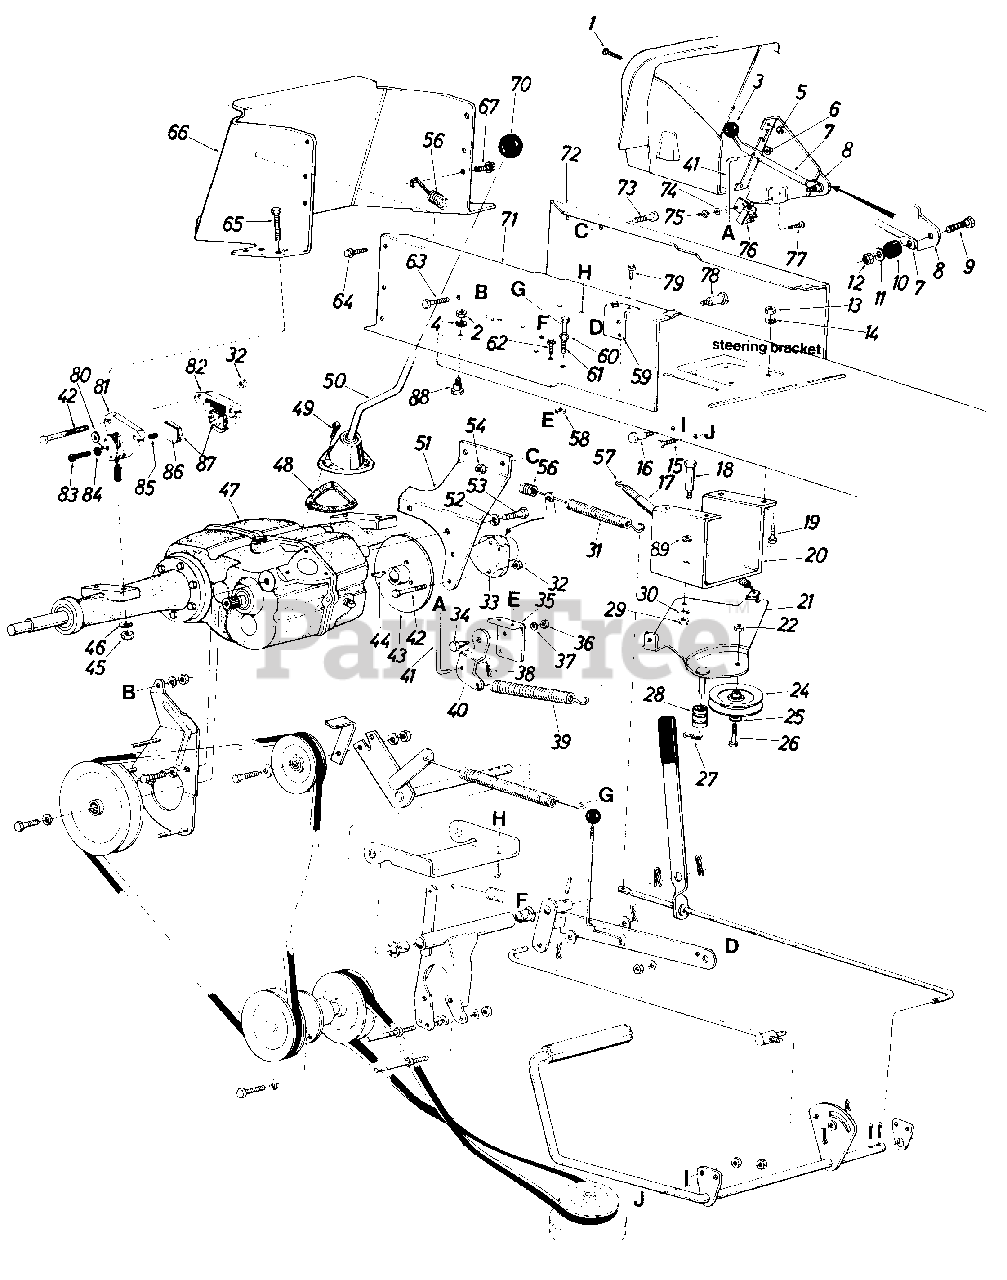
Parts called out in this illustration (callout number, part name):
1	Truss Mach. Scr. 1/4-20 x .50" Lg.
2	Hex Nut 1/4-20 Thd.
3	Knob-Blade Clutch
4	L-Wash. 1/4 I.D.
5	Hex Sems Nut 1/4-20 Thd.
6	Push Cap 1/4" Rod
7	Blade Clutch Lever
8	Deck Clutch Control Brkt.
9	Hex Scr. 1/4-20 x 1.25" Lg.
10	Rubber Wash. .330 I.D. x .87
11	Fl-Wash 1/4" I.D. x .75" O.D. x .057
12	Hex Cent. L-Nut 1/4-20 Thd.
13	Hex Nut 5/16-18 Thd.*
14	L-Wash. 5/16" I.D.
15	Hex Bolt 3/8-16 x .62" Lg.
16	Shld. Bolt 1/2" Dia. x .335 Lg. 3/8-16
17	Convoluted Conduit .50 I.D. x 4" Lg.
18	Shld. Bolt 7/16 Dia. x .16" 5/1 6-1 8
19	Hex Bolt 5/16-18 x 1.00" Lg.
20	Idler Mtg. Brkt.-Deck
21	Idler Brkt. Ass'y.
22	Hex L-Nut 3/8-16 Thd.
24	4"-"V" Idler Pulley
25	Fl-Wash. 3/8" I.D.
26	Hex Bolt 3/8-16 x 1.25" Lg.
27	Hairpin Cotter 5/16" Rod
28	Spacer
29	Hex Nut 5/16-18 Thd.
30	L-Wash. 5/16" Scr.
31	Ext. Spring-Brake Rod
32	Hex Cent. L-Nut 3/8-16 Thd.
33	Disc Brake Caliper Ass'y.
34	Shld. Scr. 7/16" Dia. x .16" Lg. 5/16-18
35	Parking Brake Cam Mtg. Brkt.
36	Hex Nut 5/16-18 Thd.
37	L-Wash. 5/16" I.D.
38	Hairpin Cotter 5/16" Dia.
39	Ext. Spring-Deck Control
40	Deck Control Pivot Brkt.
41	Deck Control Rod
42	Hex Bolt 3/8-16 x 2.50" Lg.
43	Hub & Disc Ass'y.
44	Hi-Pro Key 3/16 x 3/4" Lg.
45	Hex Nut 3/8-16 Thd.
46	L-Wash. 3/8" I.D.
47	Transaxle
51	Transaxle Support
52	L-Wash. 3/8" Scr.
53	Hex Scr. 3/8-16 x .75" Lg.
54	Hex L-Nut 3/8-16 Thd.
56	Ext. Spring-Brake Return
57	Ext. Spring-Deck Idler Return
58	Hex L-Nut 5/16-18 Thd.
59	Parking Brake Cam Mtg. Brkt.
60	Hex Nut 5/16-18 Thd.
61	Hex Bolt 5/16-18 x 1.5" Lg.
62	Hex Thd. Rolling Scr. 1/4-20 x.50" Lg.
63	Hex Bolt 3/8-16 x .75" Lg.
64	Hex AB-Tap Scr. 5/16 x .75" Lg.
65	Hex Scr. 3/8-16 x 1.50" Lg.
66	Hitch Plate
67	Hex Thd. Rolling Scr. 5/16-24 x .75" Lg.
70	Knob-Transaxle
71	Side Panel Upper Frame-R. H.
72	Side Panel Upper Frame-L. H .
73	Hex Bolt 3/8-16 x .75" Lg.
75	Hex Nut #10-24 Thd.
76	Safety Switch
77	Truss Mach. Scr. #10-24 x .50" Lg.
78	Shld. Bolt 7/16" Dia. x .16" Lg. 5/16-18
79	Hex Thd. Rolling Scr. '/4-20 x.50" Lg.
81	Housing with Lever & Pin
83	Pin, Adjuster
84	Nut
85	Pin, Actuator
86	Backing Plate
87	Lining
88	Shld. Bolt .375" Dia. x .180" Lg. 1/4-20 Thd.
89	Wave Washer
